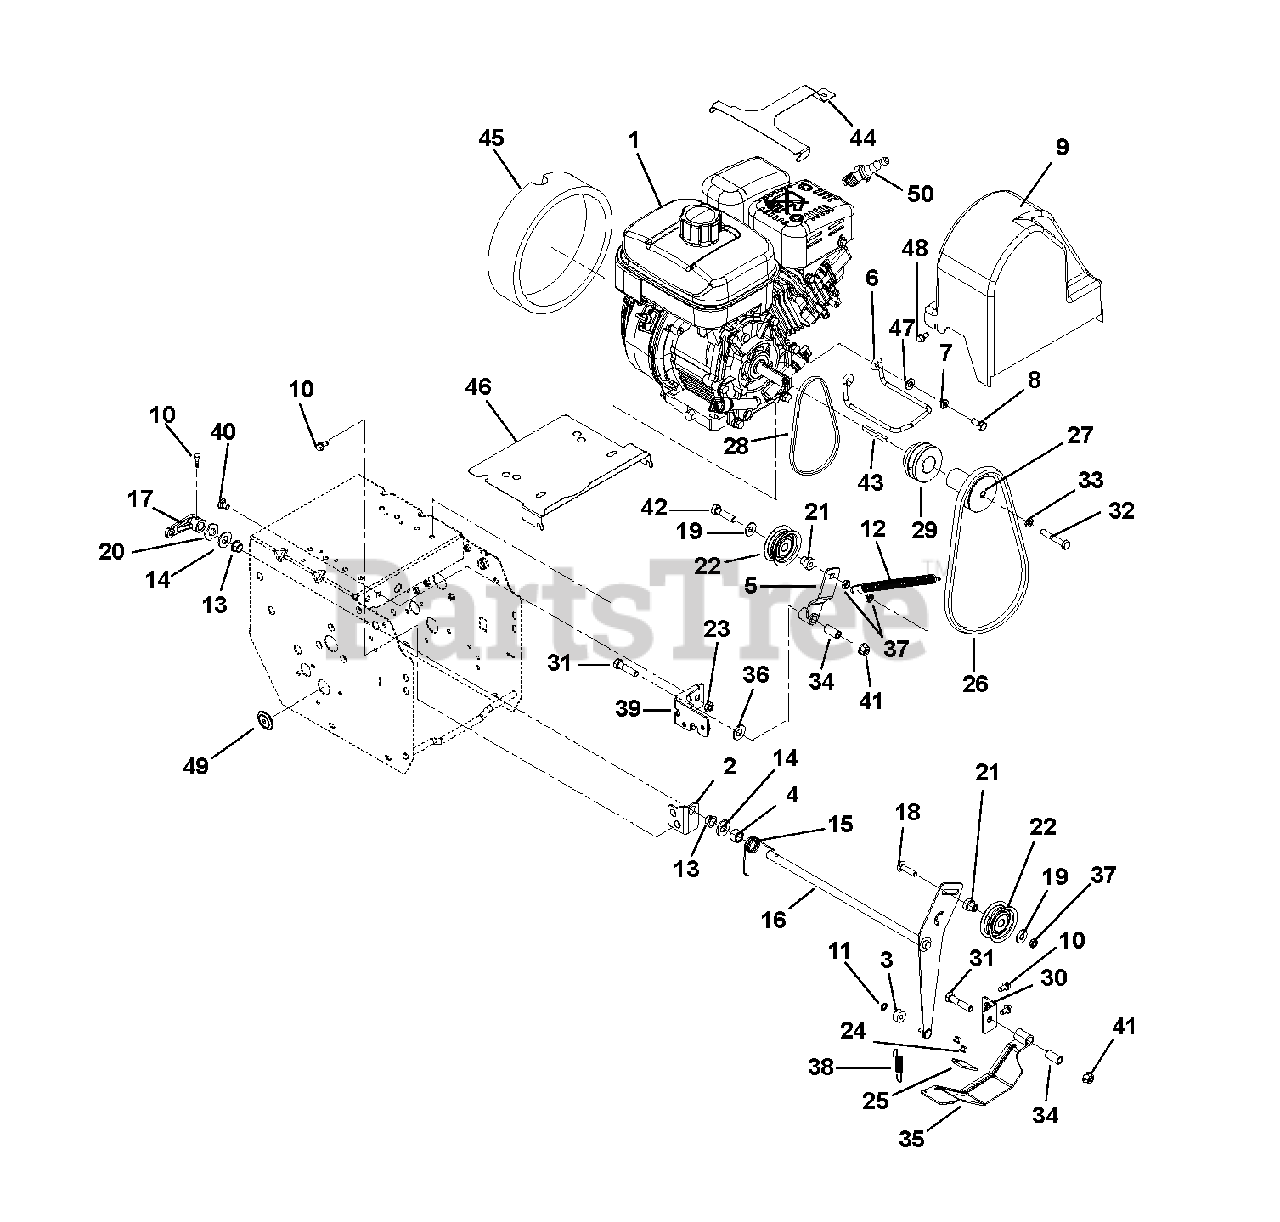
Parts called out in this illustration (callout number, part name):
1	Engine, Subaru EX17 All Season 120V
2	Bracket, Mount – Idler Arm
3	Bushing, Sleeve
4	Bushing, Sleeve
5	Traction Idler Arm
6	Belt Finger
7	Washer, Lock .31 x .097
8	Bolt, Hex .31-24 x .75
9	Belt Cover
10	Screw, Tapping Hex Washer Head Thread Rolling .25-20 x .50
11	Ring, Retaining, External .250 x .010
12	Spring
13	Bushing, Polyliner
14	Washer, Flat Steel .531 x 1.00 x .063
16	Attachment Idler Arm
17	Arm, Clutch, Attachment
18	Bolt, Round Head Square Short Neck .31-18 x 1.13
19	Washer, Flat Steel .38 x .875 x .083
20	Washer, Wave
22	Idler
23	Nut, Locking, Top, Flange .31-18
24	Rivet, Pop .187 (Included with Item 35)
25	Brake Pad (Included with Item 35)
26	V-Belt, Attachment
27	Sheave, Attachment
28	V-Belt, Traction
29	Pulley, Traction
30	Bracket, Mount, Brake
31	Bolt, Hex .38-16 x 1.75
32	Bolt, Hex .31-24 x 1.75
33	Washer, Lock .31 x .097
34	Bushing, Sleeve
35	Brake Arm w/Pad (Includes Items 24 and 25)
36	Washer, Flat Steel .406 x .812 x .065
37	Nut, Locking Center Jam .31-18
39	Frame Bracket
40	Bolt, Round Head Square Short Neck .31-18 x .62
41	Nut, Locking Top Flange .38-16
42	Bolt, Hex .31-18 x 1.50
43	Key, Square .188 x .75 x .188
44	Guard, Snow
45	Foam Cover, Recoil
47	Washer, Flat Steel .344 x .688 x .065
48	Screw, Tapping Captive .25-20 x .50
49	Plug, Hole
50	Spark Plug
